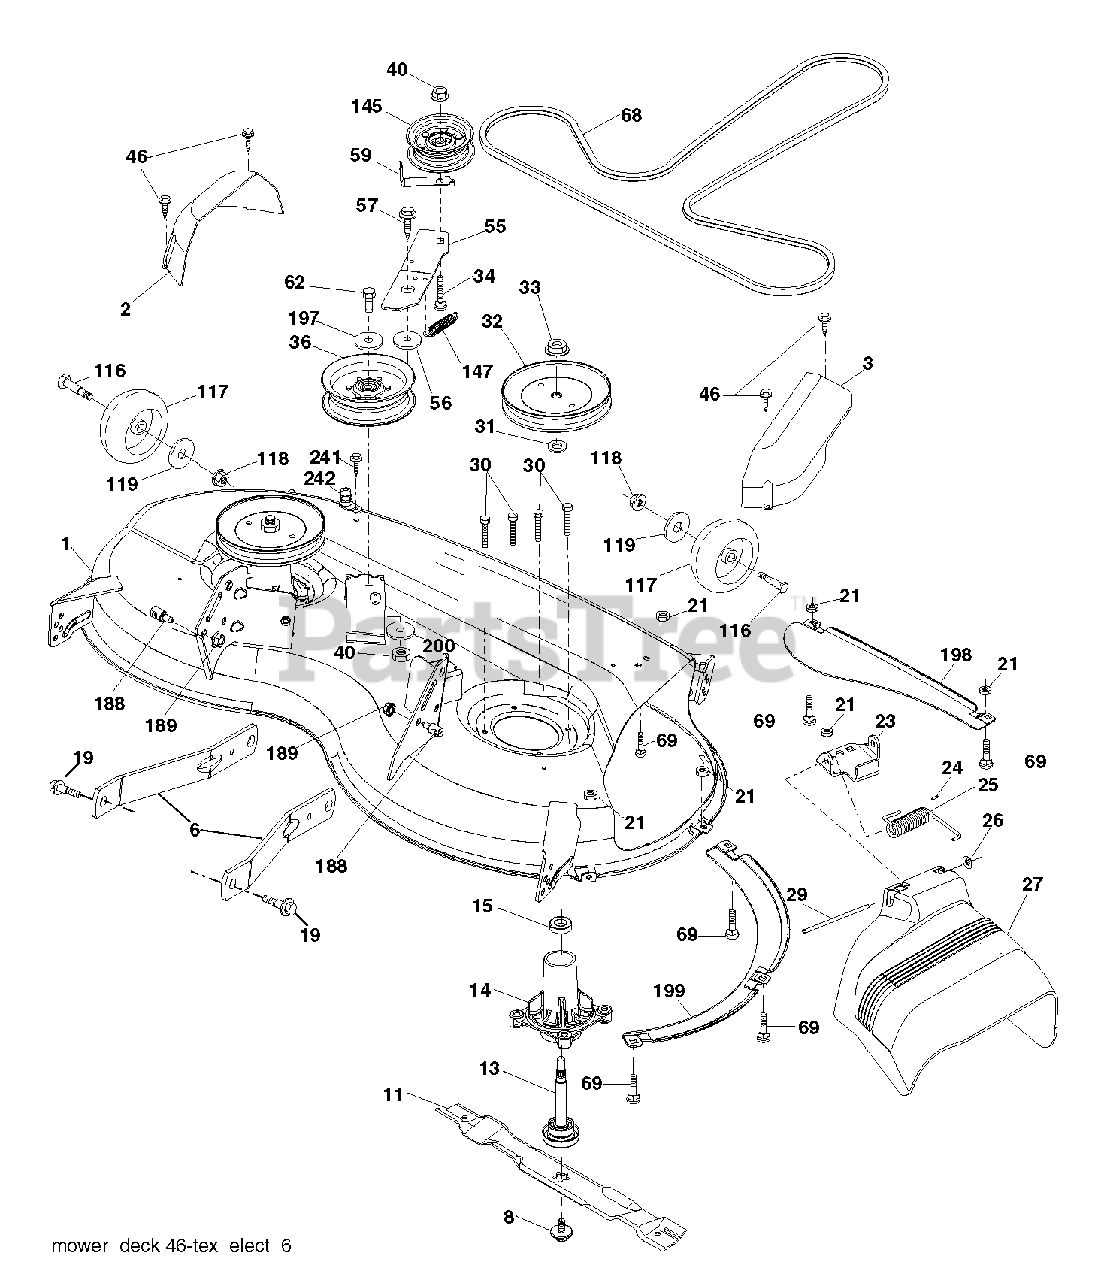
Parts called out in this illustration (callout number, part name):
1	DECK.WELDMENT.46"4GW.WHL.MS666
2	COVER MANDREL LH
3	COVER MANDREL RH
6	ARM.SUSPENSION.MOWER.R
8	BOLT.WASHER.ASM.7/16-2
11	BLADE 46" HI LIFT
13	SHAFT.ASM.MDRL.N/GREASE.38
14	HOUSING MANDREL
15	BEARING
19	BOLT.SHOULDER
23	BRKT.DEFLECTOR
24	CAP-SLEEVE LT
25	SPRING.TORSION.DEFLECT
26	NUT PUSH M
27	SHIELD, DEFLECTOR
29	HINGE ROD
30	SCREW, WASHER HEAD
33	NUT.FLANGE.LOCK.TOP
46	SCREW 1/4-20X5/8
55	IDLER.ARM
56	SPACER.RETAINER
57	SCREW 3/8-16X1
59	GUARD, BELT
62	BOLT-HEX EAK
68	V BELT
69	BOLT
117	WHEEL GAGE.HALF.SPOKED
147	SPRING.MOWER.DRIVE.ELECTRIC
188	STUD.FASTNER.W/ANTI-ROTATE
189	NUT LOCK HEX FLANGE 5/16-18
198	BAFFLE CENTER FRONT
199	BAFFLE FRONT RH
200	WASHER.13/32 X 1 X 1/2.11GUARD
242	PORT.WASHOUT
